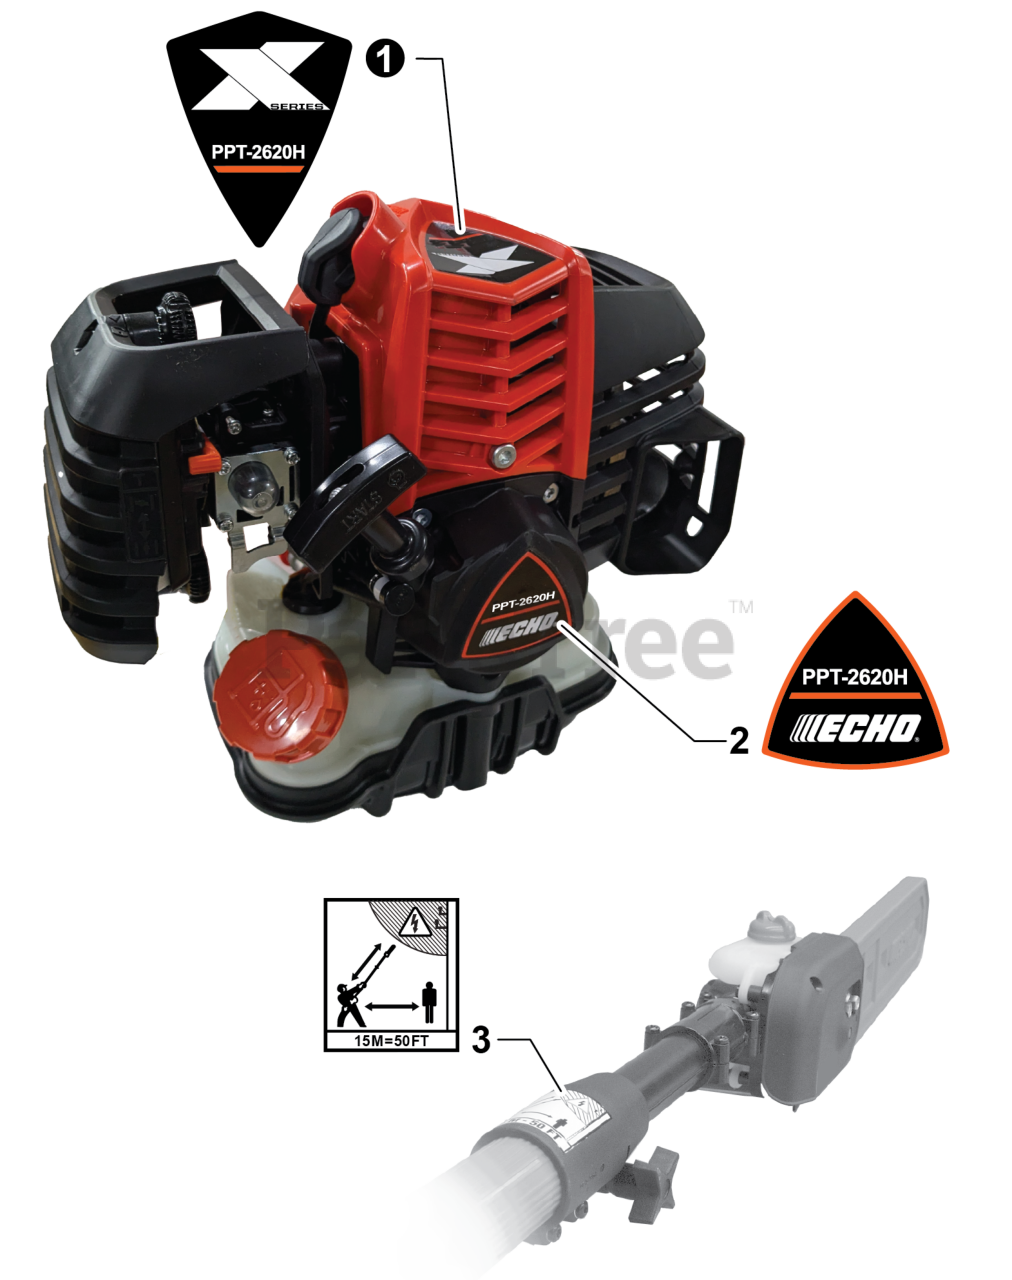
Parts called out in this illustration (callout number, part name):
1	LABEL - MODEL PPT-2620H
2	LABEL - RECOIL STARTER - PPT-2620H
3	LABEL - CAUTION
